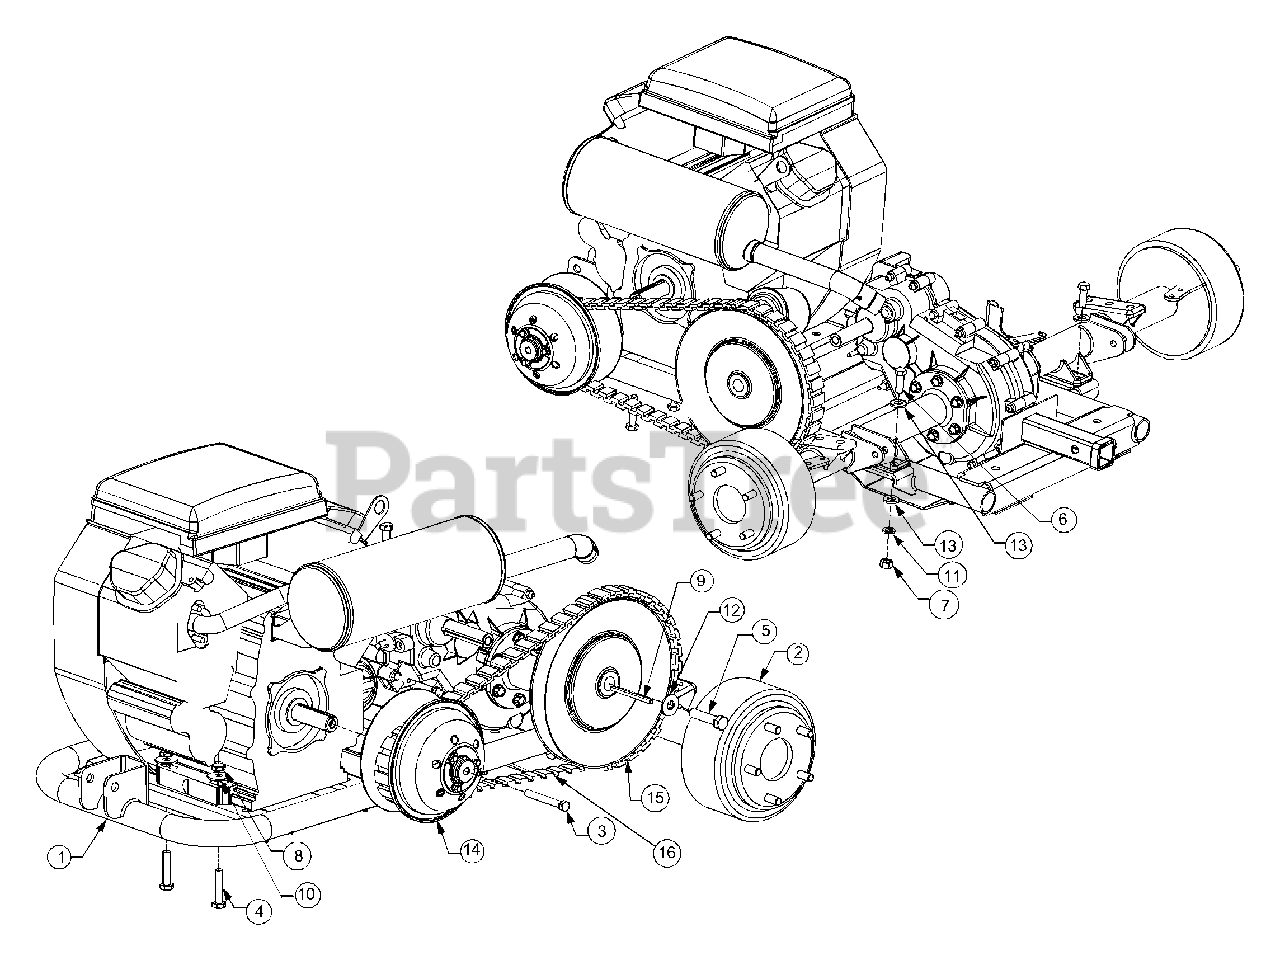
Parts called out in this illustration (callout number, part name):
1	Engine/Trans. Cradle
2	Transmission Ass'y, Diff-Lock
3	Hex Screw,3/8-24 x 3.00
4	Hex Screw, M10-1.25
5	Hex Screw, 1/2-20 x 2.25
6	Hex Screw, 7/16-20 x 1.25
7	Nut, Hex 7/16-20
8	Nut, Nylon Lock, M10-1.25
9	Key, Square 1875 x 3.25
10	Washer, Flat, .510 x 1.00 x .125
11	Washer, Lock 7/16
12	Washer, Flat, .531 ID x 1.25 X 1.
13	Washer, Flat, .510 x1.00 x .125
14	Clutch Assembly, Engine
15	Clutch Assembly, Transmission
16	V-Belt, Cogged
